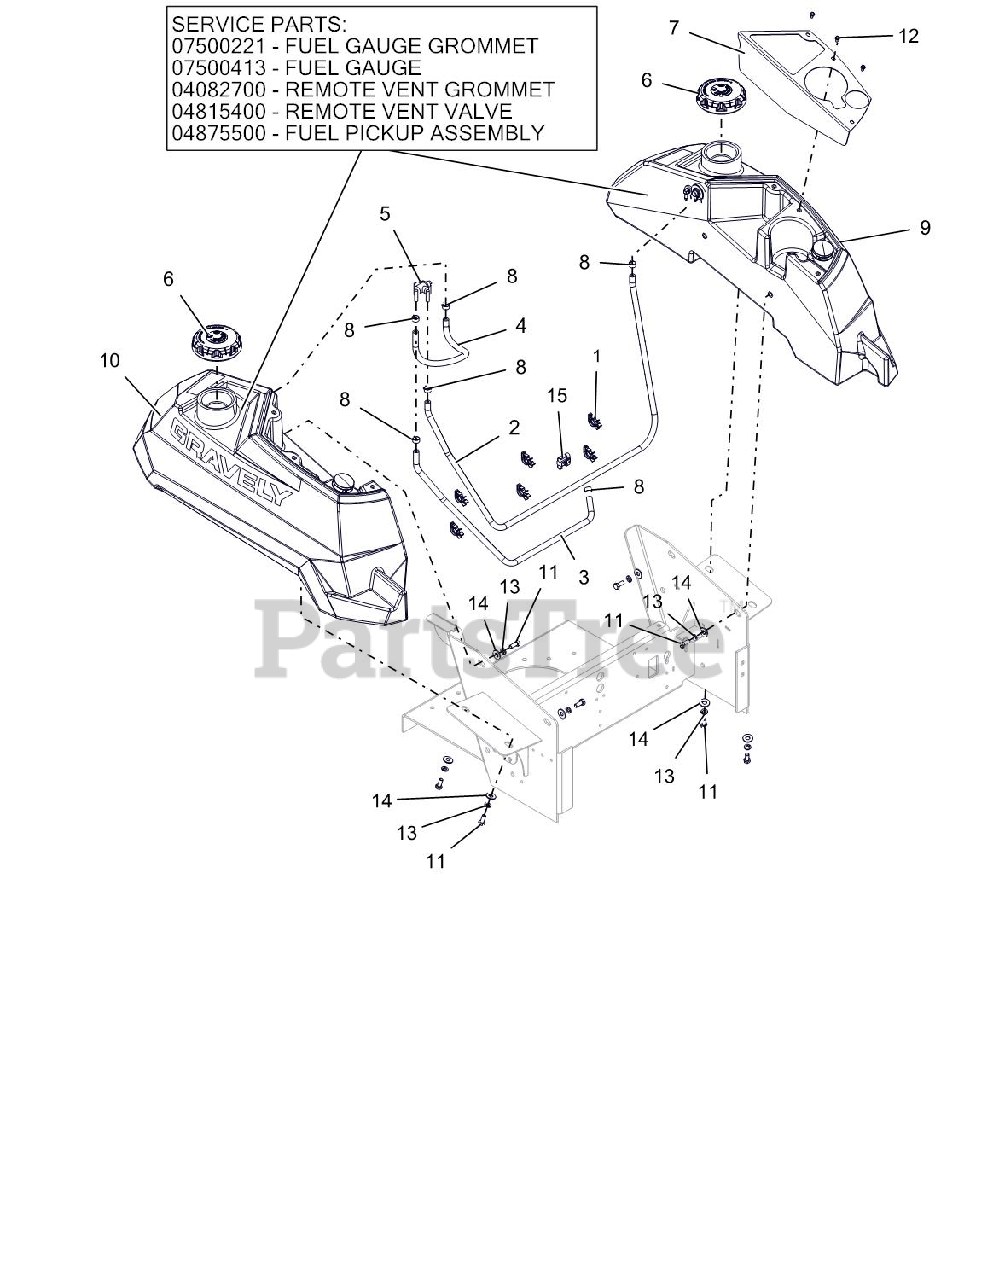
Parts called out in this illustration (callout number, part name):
1	WIRE CLIP
2	HOSE, .25 LOW-PERM BULK GAS
3	HOSE, .25 LOW-PERM BULK GAS
4	HOSE, .25 LOW-PERM BULK GAS
5	VALVE, FUEL
6	CAP, FUEL NONVENT AUTOLOCK
7	PT100 CUPHOLDER PANEL - RED
8	CLAMP, FUEL LINE
9	ASM, LH PT100 CARB FUEL TANK
10	ASM, RH PT100 CARB FUEL TANK
11	@BLT-HEX .31-18X.75 GR5 YWZC
12	SCR-MCH 10-24X.38 HWHSTAINLESS
13	@WSHR-LK .31X.078 REG YWZC
14	@WSHR-FL-STL.38X.875X.083 YWZC
15	CLIP, T, .38-.50
16	GROMMET, FUEL GAUGE
17	GAUGE, REMOTE SEALED FUEL
18	GROMMET, REMOTE VENT NITRILE
19	VALVE, 2-WAY
20	ASSM,LRG TANK FUEL PICKUP LINE
